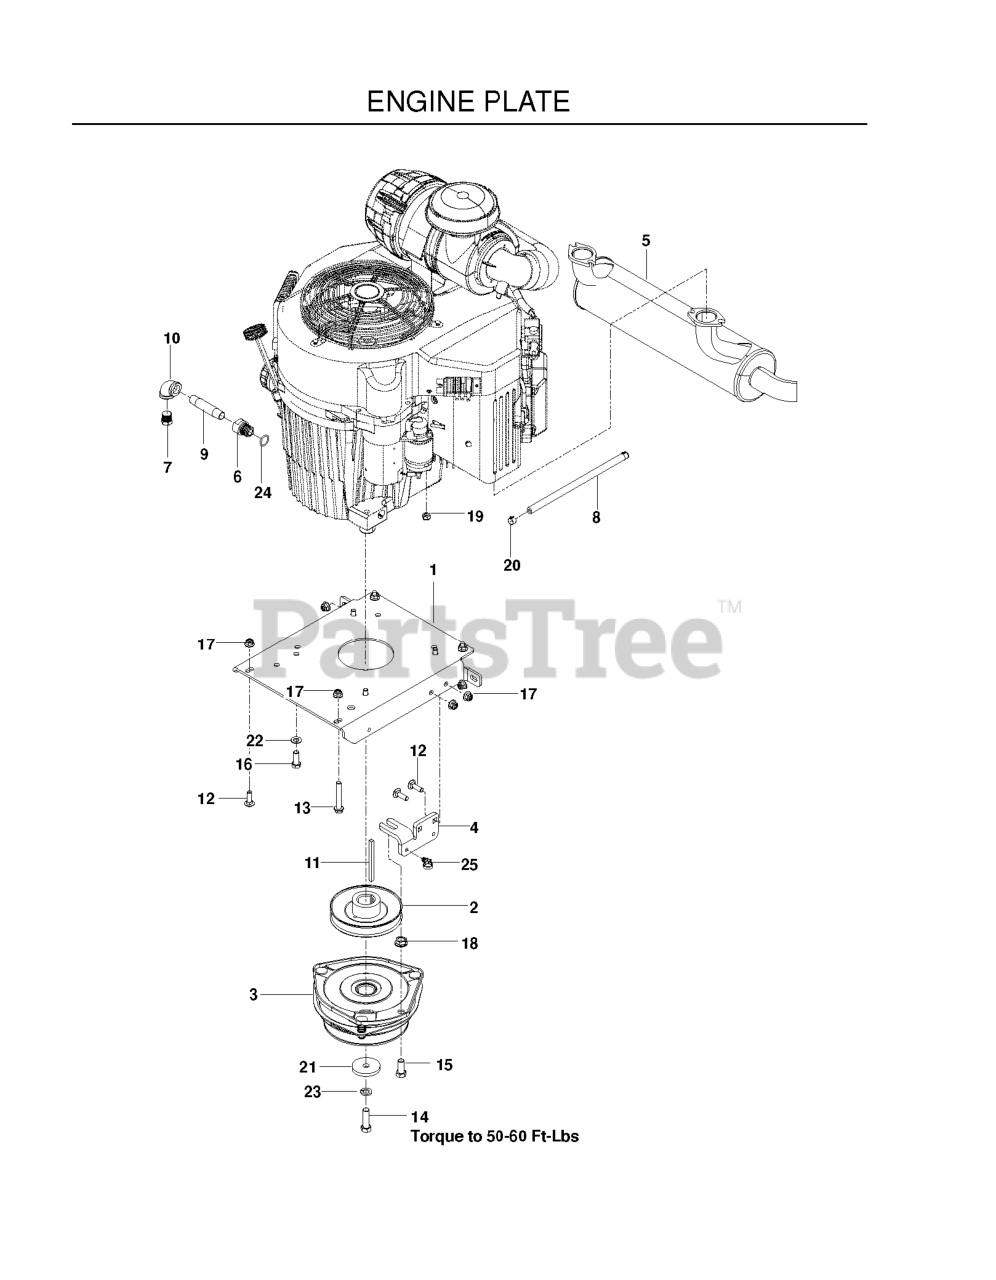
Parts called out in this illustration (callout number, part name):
1	PLATE.ENGINE.BLACK
2	PULLEY, ENGINE
3	CLUTCH, GT3.5
4	STOP, CLUTCH, OGURA
5	MUFFLER, 29HP KAW FX751V-850V
6	ADAPTER, OIL DRAIN
7	PLUG, DRAIN 3/8 NPTF
8	GAS LINE 10"
9	PIPE NIPPLE 3/8 X 3
10	90 DEG.ELBOW 3/8NPT
11	KEY, 1/4 SQ X 3.5
12	RHSNB 5/16C X 1
13	HHFS 5/16-18 X 2.25 GD 5
14	HCS 7/16F X 1 1/2
15	HCS 7/16-14 X 1 GR 5 ZD
16	HCS 3/8-16X1.GRD.5.ZD
17	5/16-18 NYLOC FLANGE NUT
18	NUT 7/16C WHIZ
19	NUT M8-1.25 TOP NYL GR10 ZD
20	HOSE CLAMP
21	BLADE WASHER
22	WASHER, 3/8 DISC SPRING SPEC
23	WASHER 7/16 LOCK
25	TIE WRAP, 8-3/8", W/CLIP
